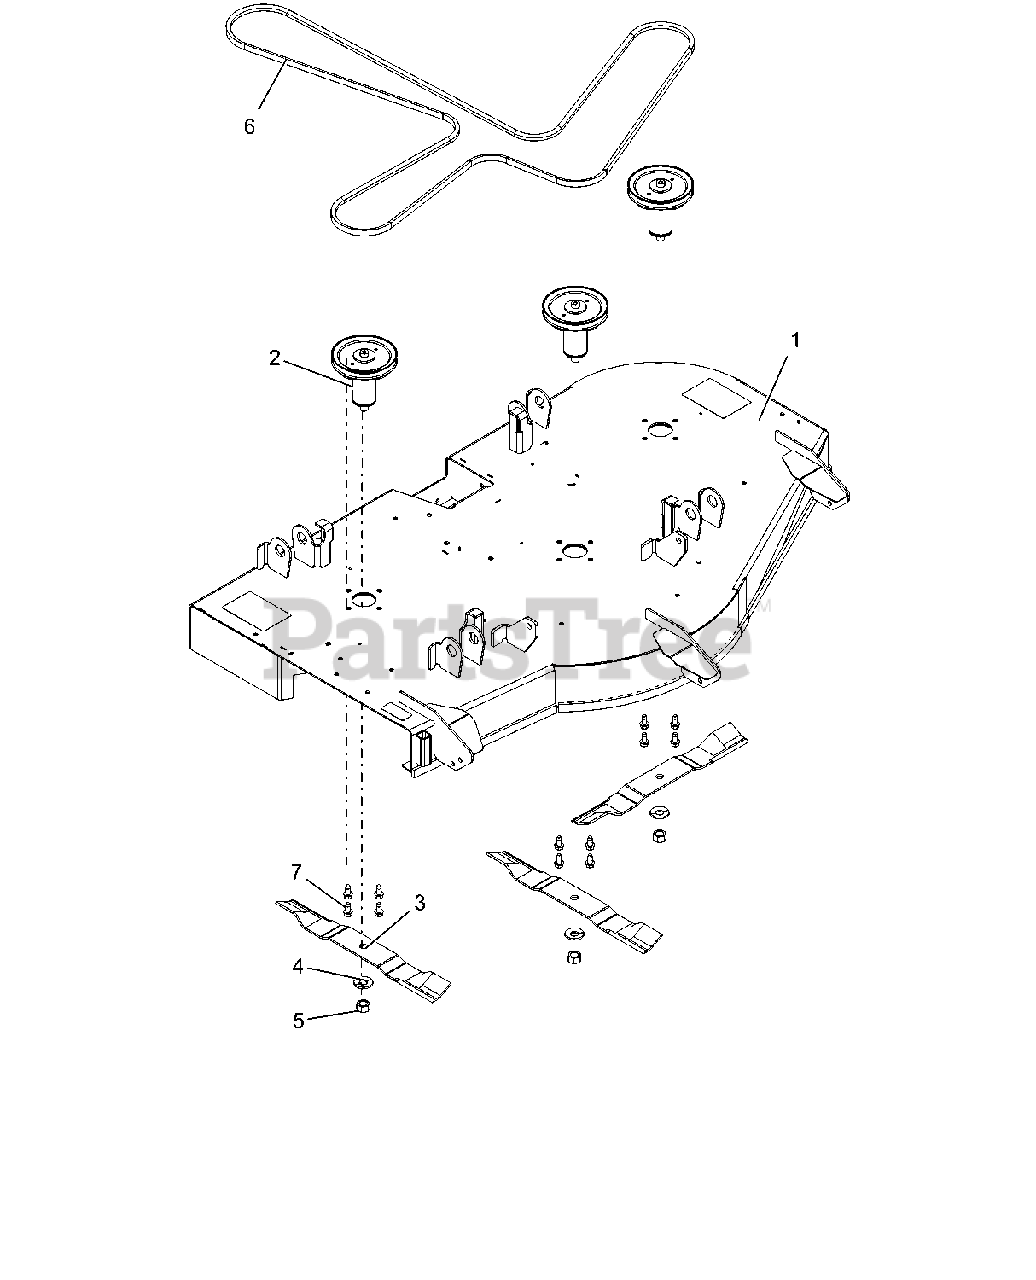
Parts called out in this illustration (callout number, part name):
1	KIT, 52" ARIENS DECK W/DECALS
2	KIT, DECK SPINDLE ASM-52
3	BLADE, 18" - 30 DEG .5 OFFSET
4	WSHR-BLVL .669X1.535X.138
5	NUT-HEX .62-18 YWZC
6	V-BELT, HA-WRAPPED
7	@SCR-TAP .38-16X.75 HWH TR YWZ
